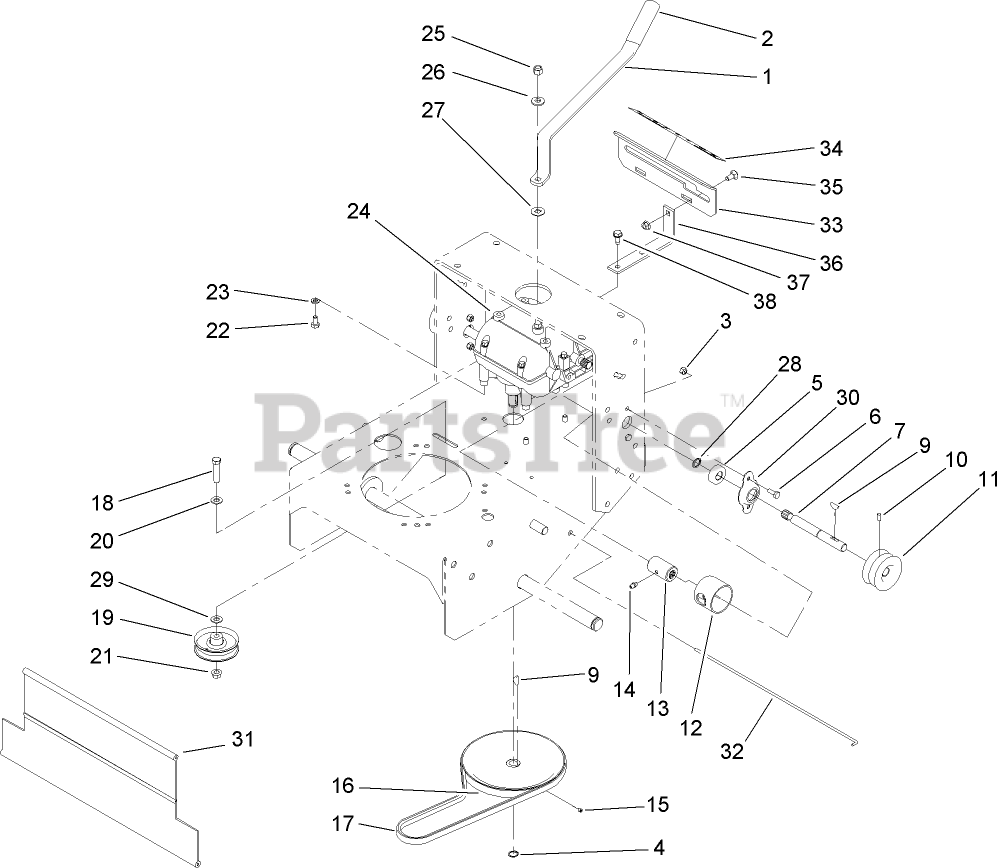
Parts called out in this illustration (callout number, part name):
1	LEVER-SHIFT
3	NUT-LOCK, NI
4	RING-SNAP, EXTERNAL
5	BEARING-SHAFT
6	SCREW-HH
7	SHAFT-OUTPUT
9	KEY-WOODRUFF
10	SCREW-SET, HSH
11	PULLEY-TRANSMISSION
12	GUARD-COUPLER
13	COUPLER
14	FITTING-GREASE
15	SCREW-SET, HSH
16	PULLEY-DRIVEN
17	BELT V
18	SCREW-HH
19	PULLEY-IDLER
20	WASHER-FLAT
21	NUT-HF
22	SCREW-HH
23	WASHER-LOCK
24	TRANSMISSION
25	NUT-LOCK
26	WASHER-BELLEVILLE
27	WASHER
28	RING-RETAINING
29	WASHER-FLAT
30	FLANGE-OUTPUT
31	SHIELD-TRAILING
32	ROD-SHIELD
33	PLATE-SHIFT
34	DECAL-SPEED, GROUND
35	BOLT-CARR
36	BRACKET-PLATE, SHIFT
37	NUT-HF
38	SCREW-HWH, THREAD CUT
